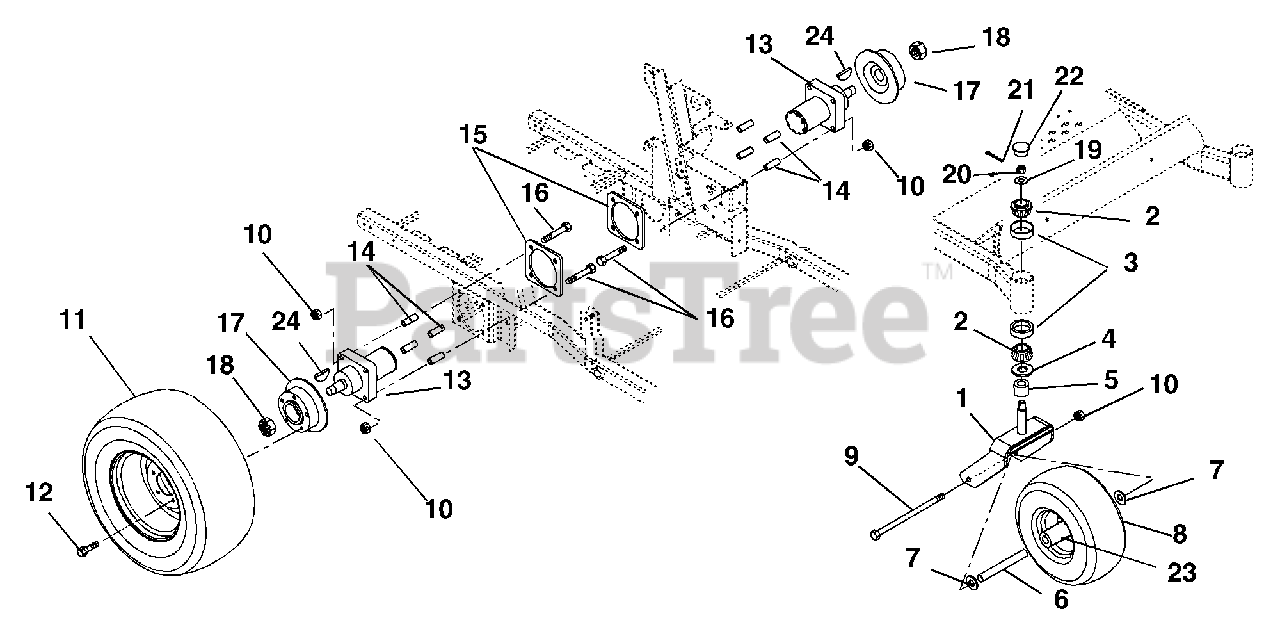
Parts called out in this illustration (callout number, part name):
1	FORK - BLACK
2	BRG, CONE W/ GREASE
3	BRG-CUP1.980X.420
4	BEARING SEAL 1.5 X 2 X .18
5	SPACER 1.005X1.5075X.375
6	SPACER - WHEEL
7	WSHR-FL-STL .515X1.625X.250 YZ
8	WHEEL/TIRE ASM
9	@BLT-HEX .50-13X9.00 GR5 YWZC
10	@NUT-LK-TOP-FLG .50-13 YWZC
11	WHL/TIRE 23X10.50-12 MULTITRAC
12	BLT, LUG .50-20 X 1.38
13	WHEEL MOTOR, MB15
14	BSHG-SLV .513X.748X2.129
15	PLATE, MOTOR SUPPORT
16	BOLT, WHEEL MOTOR 1/2-13X5.00
17	HUB & DISK (PARK) 8" 1/2 HOLE
18	NUT-LK-JAM-PTCH 1.00-20
19	WSHR-FL-STL.755X1.375X.062YWZC
20	NUT, SLOTTED .75-16
21	@PIN-CTR .16X1.00 EXTPRSQCT YZ
22	CAP,DUST
23	BRG, 25MM ID X 52MM OD X 15MM
24	KEY-WDRF .31X1.00 SFT #B
